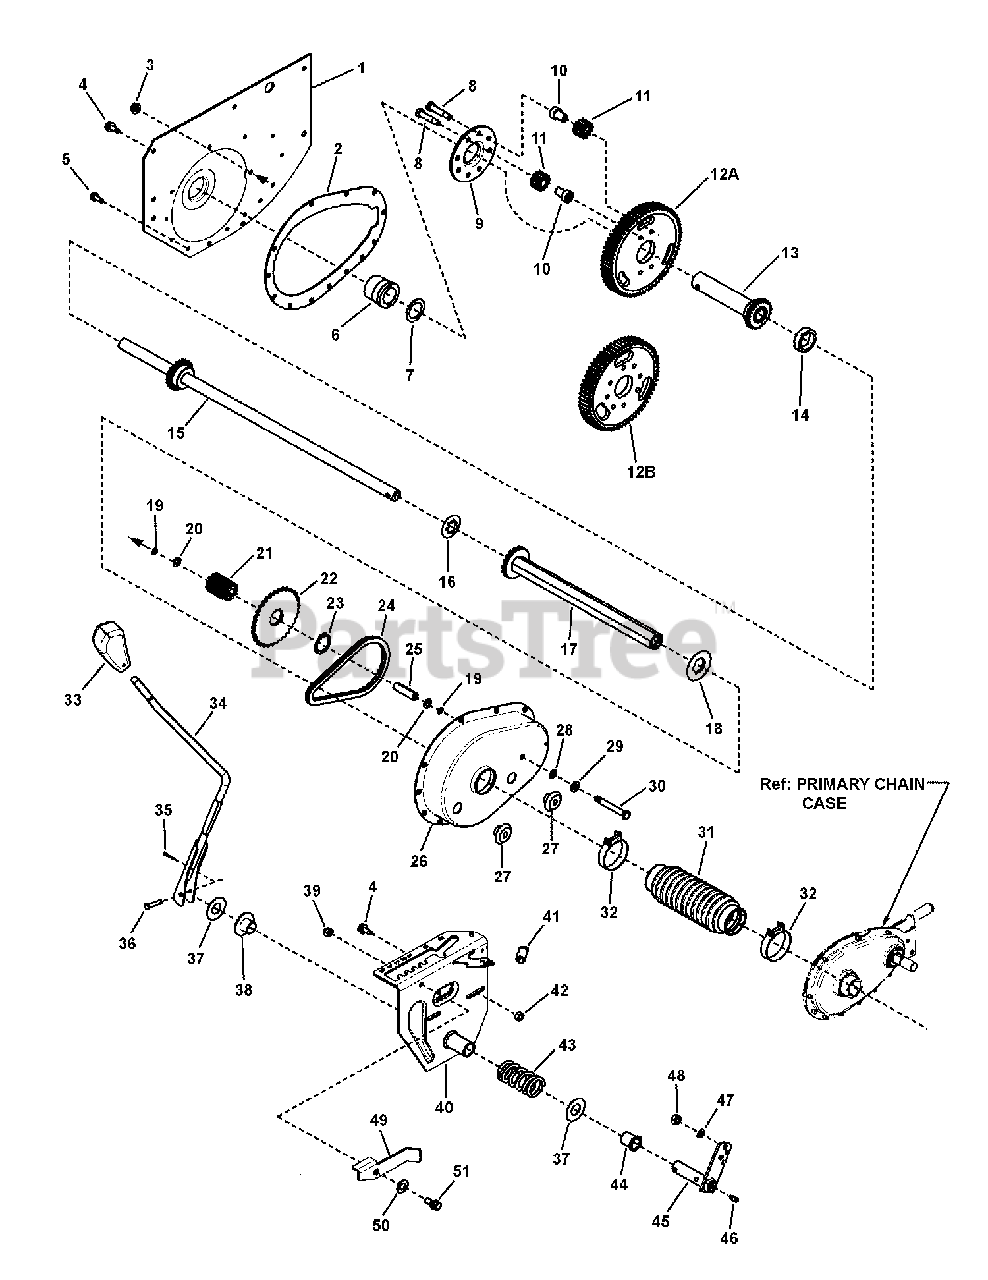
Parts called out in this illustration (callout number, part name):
1	FENDER, Right Hand (1.62" Dia. Hole)
2	GASKET, Transmission Case
3	NUT, 5/16-24 Flange Lock (Large)
4	SCREW, 5/16-18 x 5/8" Hex Washer Self-Tap
5	SCREW, 1/4-20 x 5/8" Hex Washer Head Self-Tap
6	BEARING, Axle (R. H. Fender)
6	ASSEMBLY, Axle Bearing-DX (R. H. Fender) (incl. two DX Bearings, p/n 7074183)
7	WASHER, Thrust (1.37" ID, 1.625" OD)
8	BOLT, 5/16-24 x 1-5/8" Hex Special Lock (Vibresist)
9	PLATE, Differential
10	SPACER, Pinion
11	GEAR, Differential Pinion (12T 12P)
12A	GEAR, 63 Tooth 10 Pitch (4 Hole)
12B	GEAR, 63 Tooth 10 Pitch (8 Hole)
13	ASSEMBLY, Short Axle, 23T (Includes Gear)
14	SPACER, Differential (1.25" ID x .423 Wide)
15	KIT, Long Axle (Includes welded Gear and item #14)
16	WASHER, Thrust, (Hex Flanged)
17	* ASSEMBLY, Drive Hex Tube
18	WASHER, Nylon
19	O-RING, 5/16"
20	WASHER, 5/16" Belleville
21	GEAR, 11 Tooth, 10 Pitch
22	SPROCKET, 34T, 3/8P
23	RING, 1-3/16" External Retaining
24	CHAIN, 46 Pitch (#35 Endless)
25	SPACER, Differential Case
26	CASE, Transmission
27	PLUG, 1/2" Cup Insert
28	WASHER, 5/16" External Tooth Lock
29	WASHER, .34 x .69 x .08 Flat
30	SCREW, 5/16-24 x 2-5/8" Hex Head Cap
31	BOOT, Oil Seal (Short Axle)
32	BOOT CLAMP, 2"
33	GRIP, Shift Handle
34	WELDMENT, Shift Handle
35	PIN, 3/32 x 3/4" Cotter
36	PIN, 1/4 x 1-3/4" Tapered Clevis
37	WASHER, Thrust (.76" ID, 1.63" OD)
38	BUSHING, 3/4 x 1.62 Flange (Nylon)
39	NUT, 5/16-18 Hex Nyloc
40	** ASSEMBLY, Speed Adjustment Latch
41	SPRING
42	NUT, 5/16-18 Hex, GR 5 or B
43	SPRING, Shift Detent
44	BUSHING, 3/4 x I.O. Flange (Nylon)
45	WELDMENT, Arm, Shift Handle (w/grease fitting. Hole)
46	LUBE FITTING, 3/16" Press-In
47	WASHER, .32 x .58 x .08 Split Lock
48	NUT, 5/16-24 Hex, GR 5
49	LEVER, Over-Ride
50	WASHER, .47 x .92 x .065 Flat
51	BOLT, Shoulder, 5/16-18
